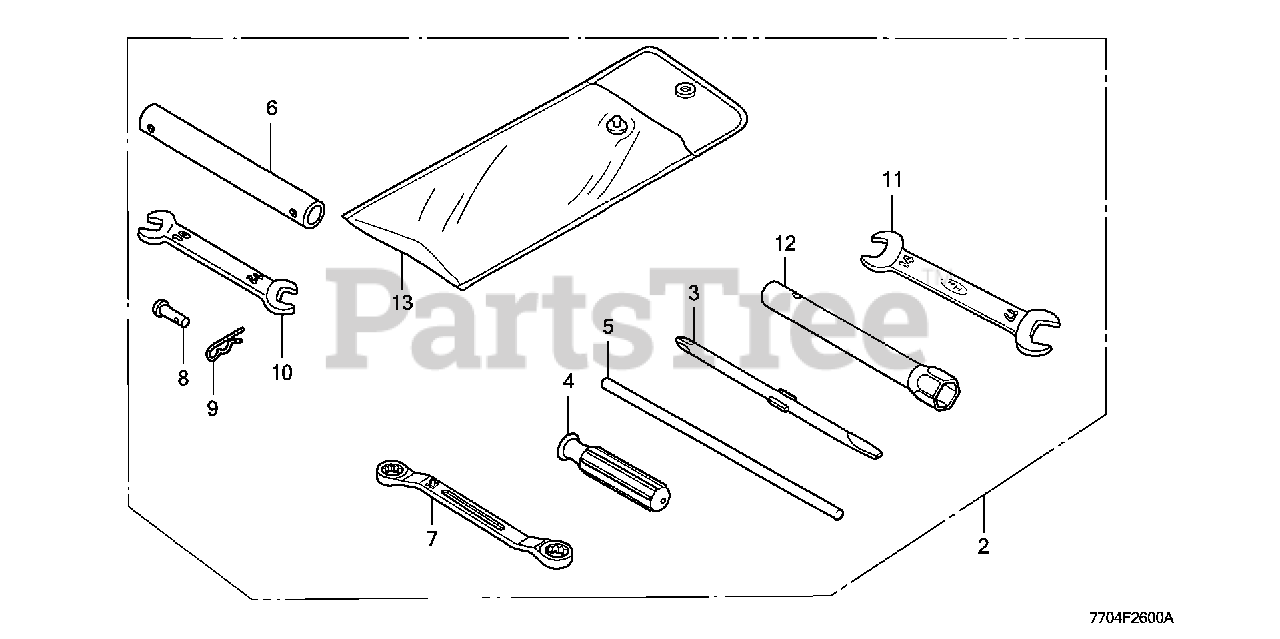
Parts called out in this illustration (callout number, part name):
2	TOOL KIT
3	SCREWDRIVER (NO.2 PHILLIPS -)
4	GRIP
5	HANDLE, BOX WRENCH
6	PIPE, BOX WRENCH EXTENSION
7	WRENCH, EYE (10X12)
8	PIN, ROLLER ARM (8X22)
9	PIN, LOCK (8MM)
10	SPANNER (10X12)
11	SPANNER (14X17)
12	WRENCH, BOX (P21)
13	BAG, TOOL (230MM)
